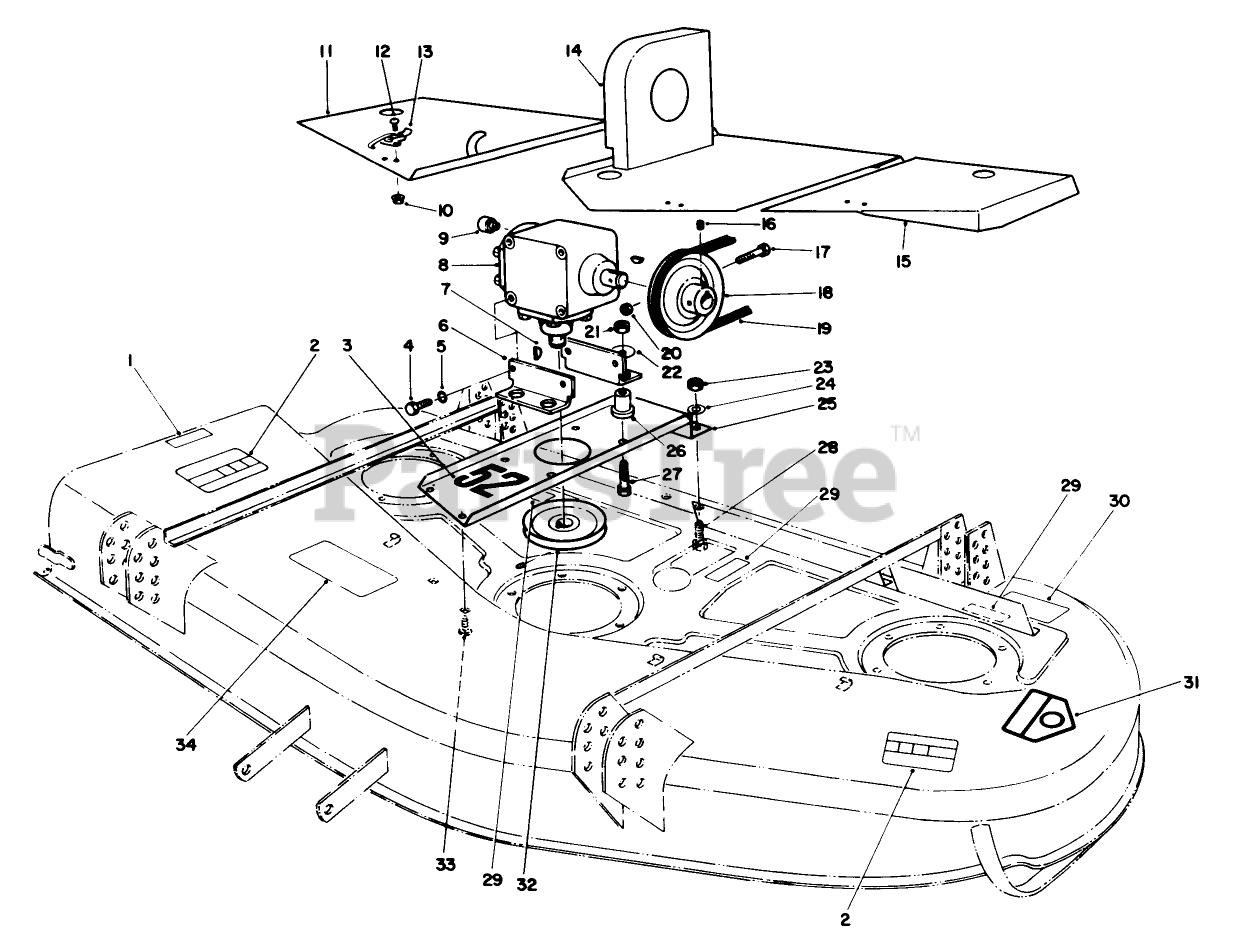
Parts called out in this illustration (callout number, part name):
1	DECAL-DANGER
2	DECAL-DANGER, THROWN OBJECT
3	DECAL
4	SCREW-HH
5	WASHER-LOCK
6	Bracket Mounting
8	Gear Box
9	FITTING-LUBE
10	NUT-LOCK, FLANGE
11	Bolt
12	SCREW-HWH
13	CLAMP-SLOTTED
14	Center-Cover
15	Cover-Deck
16	SCREW-SET, SQH
17	SCREW-HH
18	PULLEY
19	V-BELT, DECK
20	NUT-LOCK, NI
21	NUT-LOCK, SIDE
22	WASHER
23	NUT-LOCK, NI
24	WASHER-FLAT
25	Base-Gear Box Mount
26	MOUNT
27	SCREW-HH
28	SCREW-HH
29	DECAL-DANGER
30	DECAL-TORQUE
31	DECAL-DANGER
32	PULLEY
33	BOLT-CARR
34	DECAL-WARNING
